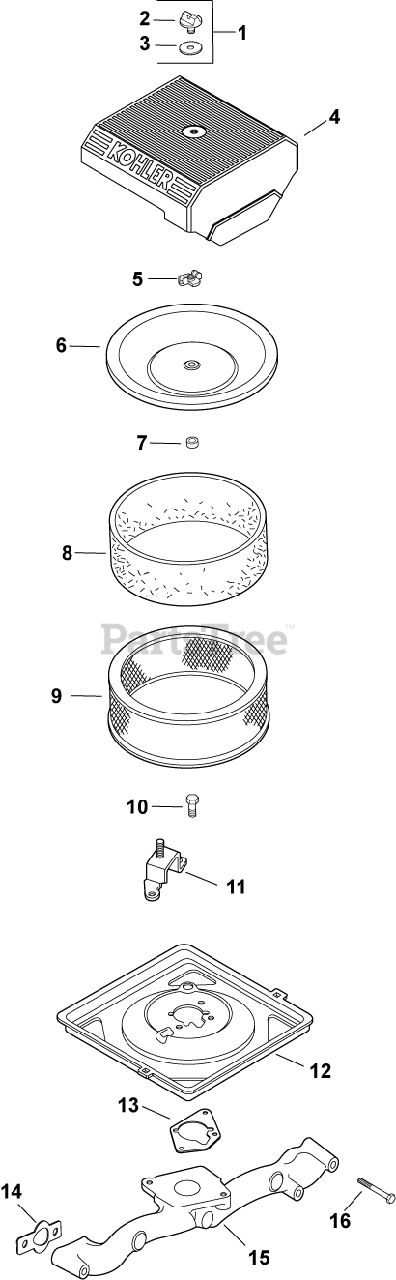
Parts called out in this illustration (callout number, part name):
1	KIT, KNOB W/SEAL
2	KNOB, COVER
4	COVER, AIR CLEANER
5	NUT, WING
6	COVER, INNER AIR CLEANER
7	SEAL, BREATHER
8	PRE-CLEANER (HIGH)
9	ELEMENT, AIR FILTER (HIGH) - Also available Retail Packaged 24 883 03-S1 Air Filter Kit
10	SCREW,FLG THD FRM M6X1.0X16-(#25086397S)
11	BRACKET, AIR CLEANER-USE 24 126 210-S
13	GASKET, AIR CLEANER BASE
14	GASKET, INTAKE MANIFOLD USE 24 041 79-S
15	MANIFOLD, METAL INTAKE
16	SCREW, FLG M6X1.0X55
